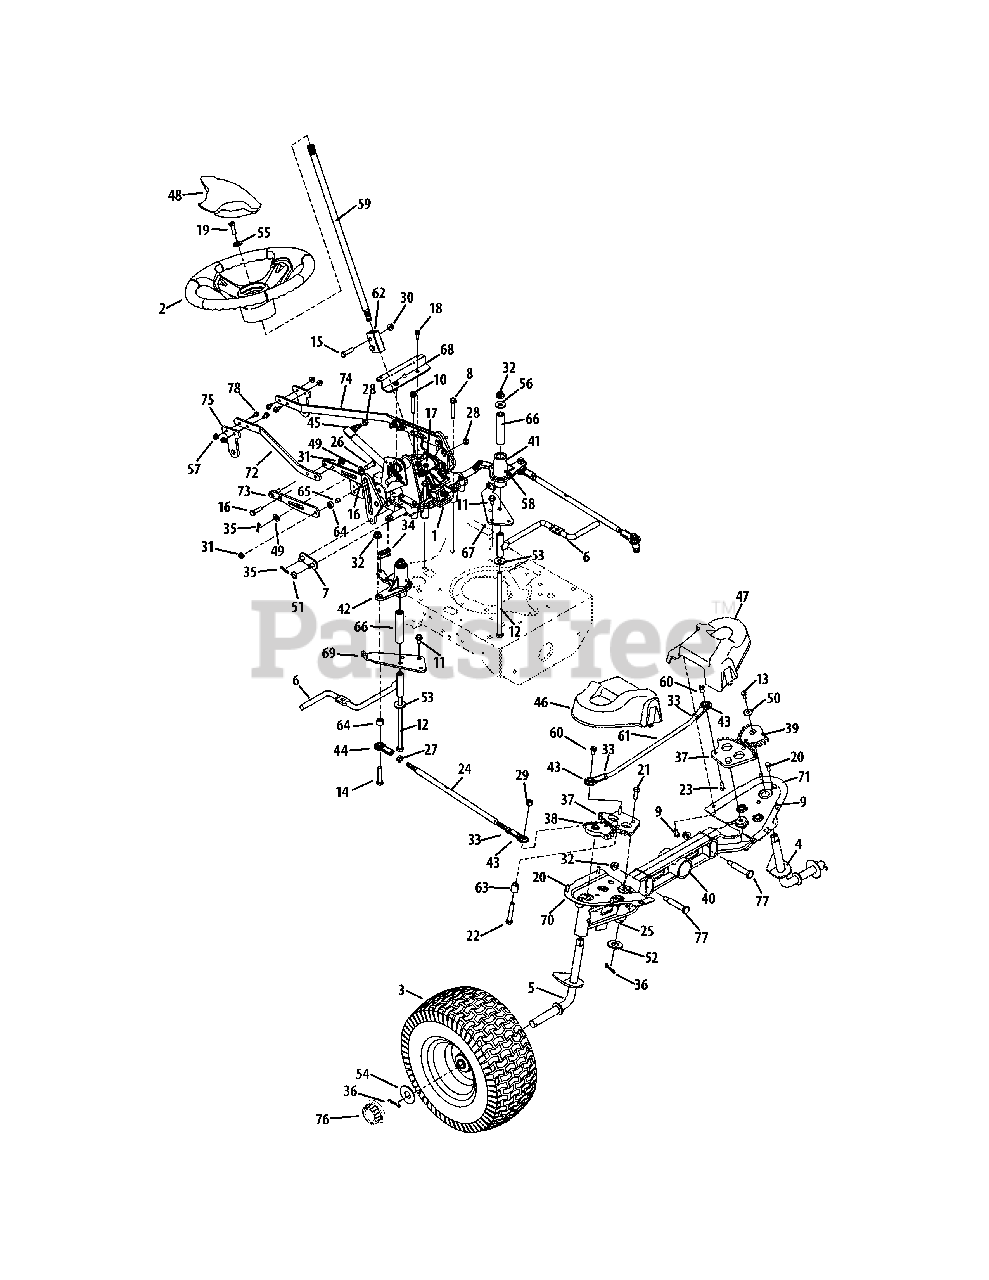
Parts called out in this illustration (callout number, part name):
1	Hydro Steering Assembly
2	Steering Wheel Assembly
3	Wheel Assembly 15 x 5.0 x 6 (42")
3	Wheel Assembly 15 x 6 x 6 (50")
4	LH Axle Assembly (42")
4	LH Axle Assembly (50")
5	RH Axle Assembly (42")
5	RH Axle Assembly (50")
6	Fender Support Rod
7	Steering Box/Hydro Link
8	Hex Washer Screw, 5/16-18 x 2.0
9	Hex Washer Screw, 1/4-15 x .5
10	Hex Washer Screw, 5/16-18 x 2.25
11	Hex Washer Screw, 5/16-18 x .75
12	Hex Screw, 3/8-16 x 7.25
13	Hex Lock Screw, 1/4-28 x .625
14	Hex Screw, 3/8-16 x 1.5
15	Hex Screw, 5/16-18 x 1.25
16	Hex Screw, 1/4-20 x 1.0
17	Hex Washer Screw, 1/4-20 x .5
18	Hex Washer Screw, 1/4-20 x .75
19	Hex Wash Screw, 5/16-18 x .875
20	Hex Screw, 1/4-20 x .75
21	Hex Lock Screw, 3/8-16 x .75
22	Hex Screw, 3/8-16 x 2.0
23	Hex Lock Screw, 1/4-20 x .75
25	Steering Pivot Gear Shaft
26	Clevis Pin, .375 x .969
27	Jam Nut, 3/8-24
28	Hex Lock Nut, M8 x 1.25
29	Hex Lock Nut, 3/8-16
30	Flange Lock Nut, 5/16-18
31	Flange Lock Nut, 1/4-20
32	Flange Lock Nut, 3/16-16
33	Hex Jam Nut, 3/8-24
34	Connecting Link
35	Bow-Tie Cotter Pin
36	Cotter Pin, 5/32 x 1.25
38	RH Spur Gear
39	LH Spur Gear
40	Pivot Bar Axle
41	LH Steering Arm
42	RH Steering Arm
43	Ball Joint Rod End
44	Ball Joint Rod End
45	Damper Cylinder
46	RH Steering Gear Cover
47	LH Steering Gear Cover
48	Steering Wheel Cover
49	Flat Washer, .375 x .738 x .063
50	Bell Washer, .265 x .75 x .062
51	Spring Washer, .39 x .75 x .010
52	Flat Washer, .76 x 1.5 x .12
53	Bell Washer, .396 x 1.14 x .095
54	Flat Washer, .755 x 1.92 x .060
55	Flat Washer, .406 x .875 x .105
56	Flat Washer, .406 x 1.0 x .105
57	Flange Lock Nut, 1/4-20
58	Grease Fitting
59	Steering Shaft, .625 x 17.281
60	Shoulder Nut, .375 x .5
61	Rod, 3/8-24 x 14.4
62	Steering Shaft Block
63	Spacer, .385 x .63 x .75
64	Spacer, .380 x .625 x .265
65	Spacer, .26 x .372 x .33
66	Spacer, .385 x .75 x 3.47
67	LH Steering Support Bracket
68	Upper Steering Support Bracket
69	RH Steering Support Bracket
70	RH Base Cover Plate
71	LH Base Cover Plate
72	RH Steering/Hydro RH Link
73	Hydro/Steering Adjust. Bracket
74	LH Steering/Hydro Link
75	Steering Link Bracket
77	Shoulder Bolt, 3/8-16 x .5 x 2.23
78	Hex Cap Screw, 1/4-20 x 1.0
